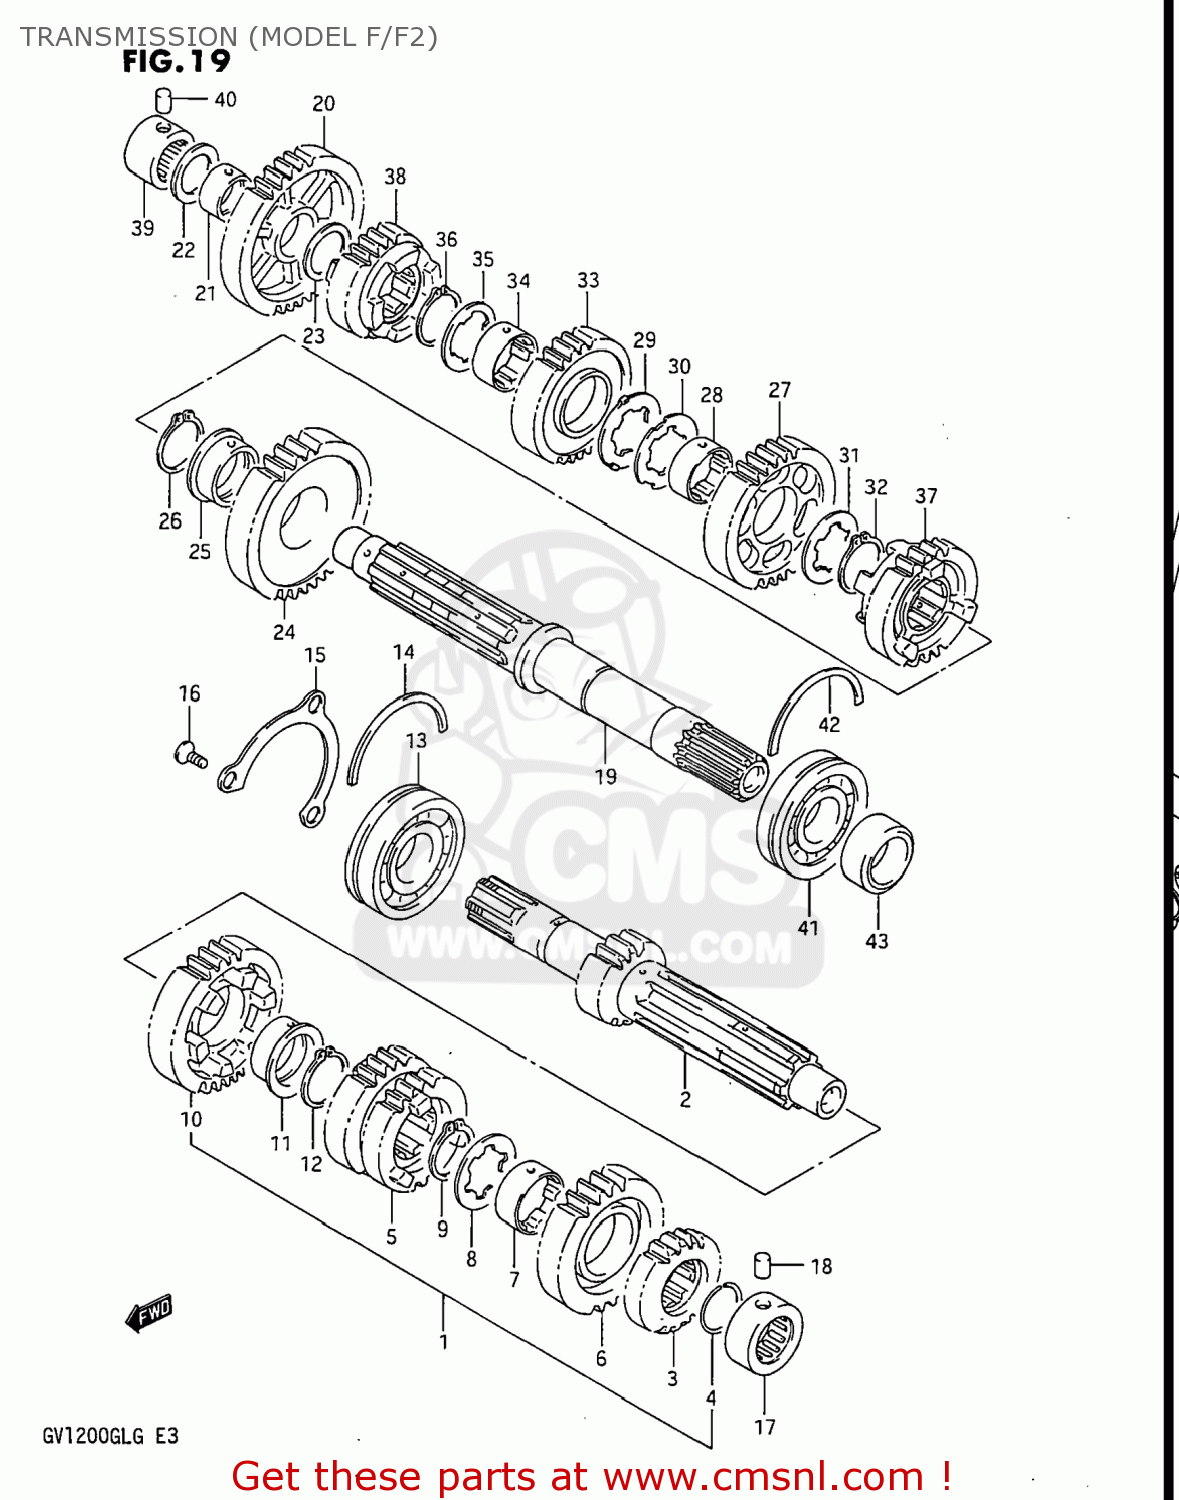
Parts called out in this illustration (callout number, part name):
1	SHAFT,COUNTER
2	COUNTER SHAFT
3	GEAR,SECOND DRIVE
4	CIRCLIP
5	GEAR,THIRD/FOURTH DRIVE
6	GEAR,FIFTH DRIVE
7	BUSH,3RD DRIVEN GEAR
8	WASHER,LOCK
9	CIRCLIP
10	GEAR,SIXTH DRIVE
11	BUSH(28X32X2)
12	CIRCLIP
13	BEARING(25X62X17)
14	C-RING
15	PLATE,COUNTERSHAFT BEARING
16	SCREW
17	ROLLER BEARING (20X36X1
18	PIN
19	SHAFT,DRIVE
20	GEAR,FIRST DRIVEN
21	BUSHING
22	WASHER
23	WASHER
24	GEAR,SECOND DRIVEN
25	BUSH(28X32X2)
26	CIRCLIP
27	GEAR,THIRD DRIVEN
28	BUSH,3RD DRIVEN GEAR
29	WASHER
30	WASHER,LOCK
31	WASHER,LOCK
32	CIRCLIP
33	GEAR,FOURTH DRIVEN
34	BUSH,3RD DRIVEN GEAR
35	WASHER,LOCK
36	CIRCLIP
37	GEAR,FIFTH DRIVEN
38	GEAR,SIXTH DRIVEN
39	BEARING(20X34X20)
40	PIN
41	BALL BEARING 25X62X17
42	C-RING
43	SPACER,DRIVESHAFT,LEFT
